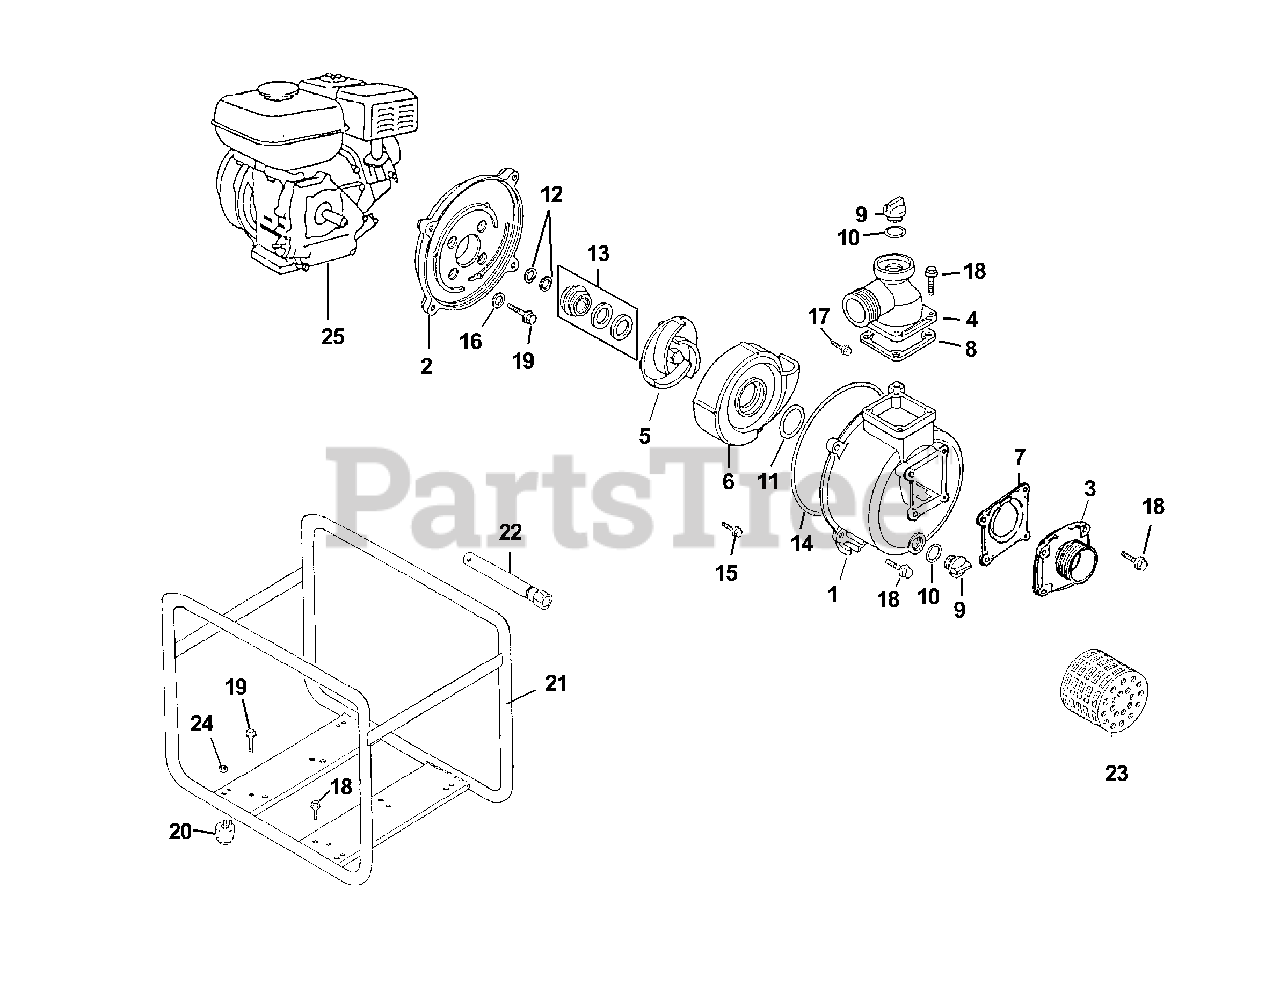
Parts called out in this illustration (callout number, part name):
2	Cover, Casing
3	Inlet Pipe 3" NPT
4	Outlet Pipe 3" NPT
5	Impeller
6	Case, Volute
7	Check Valve, Inlet
8	O-Ring 86 x 3.5
9	Cap, Filler
10	O-Ring 24 x 3.5
11	O-Ring 70 x 5.7
12	Shim, Adjuster 3mm
13	Seal, Mechanical
14	O-Ring 225 x 3.5
15	Bolt, Flange 6 x 60
16	Washer, 8mm
17	Bolt, Flange 6 x 50
18	Bolt, Flange 8 x 25
19	Bolt, Flange 8 x 28
20	Foot, Rubber
21	Frame Complete
22	Wrench, Spark Plug
23	Strainer
24	Nut, Hex 6mm
